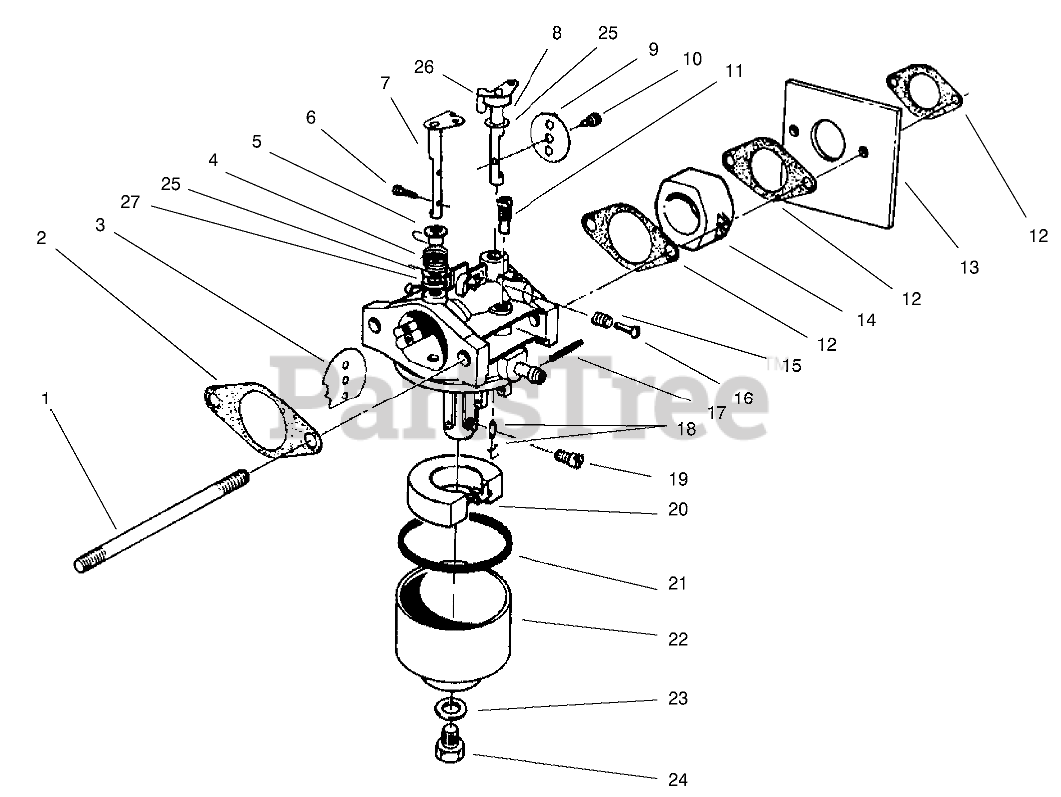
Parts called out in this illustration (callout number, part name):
1	STUD-CARBURETOR
2	GASKET-AIR CLEANER
3	PLATE
4	SPRING
5	BUSHING
6	SCREW
7	SHAFT-CHOKE
8	SHAFT
9	PLATE
10	SCREW
11	JET-PILOT
12	GASKET-CARB
13	SHIELD-CARBURETOR
14	INSULATOR-CARBURETOR
15	SPRING-PILOT SCREW
16	SCREW
17	PIN-HINGE
18	NEEDLE
19	JET-MAIN
19	JET-HIGH ALTITUDE
20	FLOAT
21	GASKET
22	BOWL - FLOAT
23	GASKET
24	SCREW
27	PACKING
